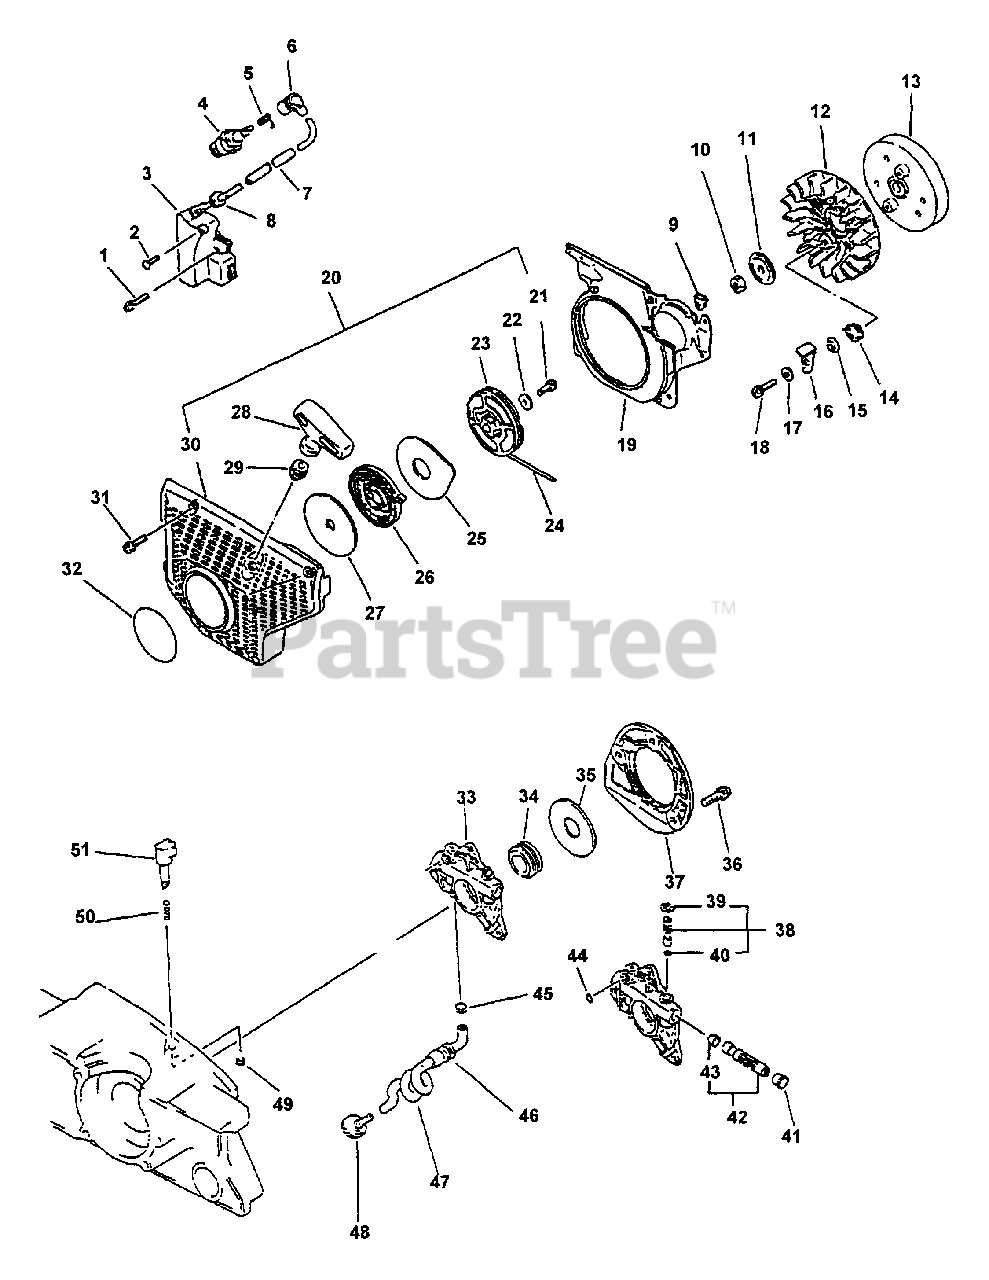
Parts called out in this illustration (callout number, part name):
1	SCREW - 4X20
2	SCREW - 4X8
3	COIL, IGNITION
4	SPARK PLUG -- CJ-6Y
5	TERMINAL, SPARK PLUG CAP
6	CAP, SPARK PLUG
11	WASHER - CUP
13	FLYWHEEL
14	SPRING, RETURN
16	PAWL, STARTER
17	WASHER - 5
18	SCREW - 5X14
19	SHIELD, FAN
20	STARTER ASSY
21	SCREW - 5X14
22	WASHER - 5
23	REEL, ROPE
24	ROPE, STARTER
25	PLATE, STARTER
26	SPRING, REWIND
27	PLATE, STARTER
28	GRIP, STARTER
29	GUIDE, ROPE
30	CASE, STARTER
31	SCREW - 5X18
32	LABEL - ECHO
33	AUTO-OILER ASSY
34	GEAR - WORM
35	WASHER - 12
36	SCREW - 4X12
37	COVER, OIL PUMP
38	CONTROL PIN ASSY
41	CAP, PLUNGER
42	PLUNGER KIT
44	O-RING - 3
45	CLIP - 6.5
47	PIPE, OIL - SPIRAL
48	FILTER, OIL
49	RING, RETAINING - 3
51	DIAL, AUTO-OILER
